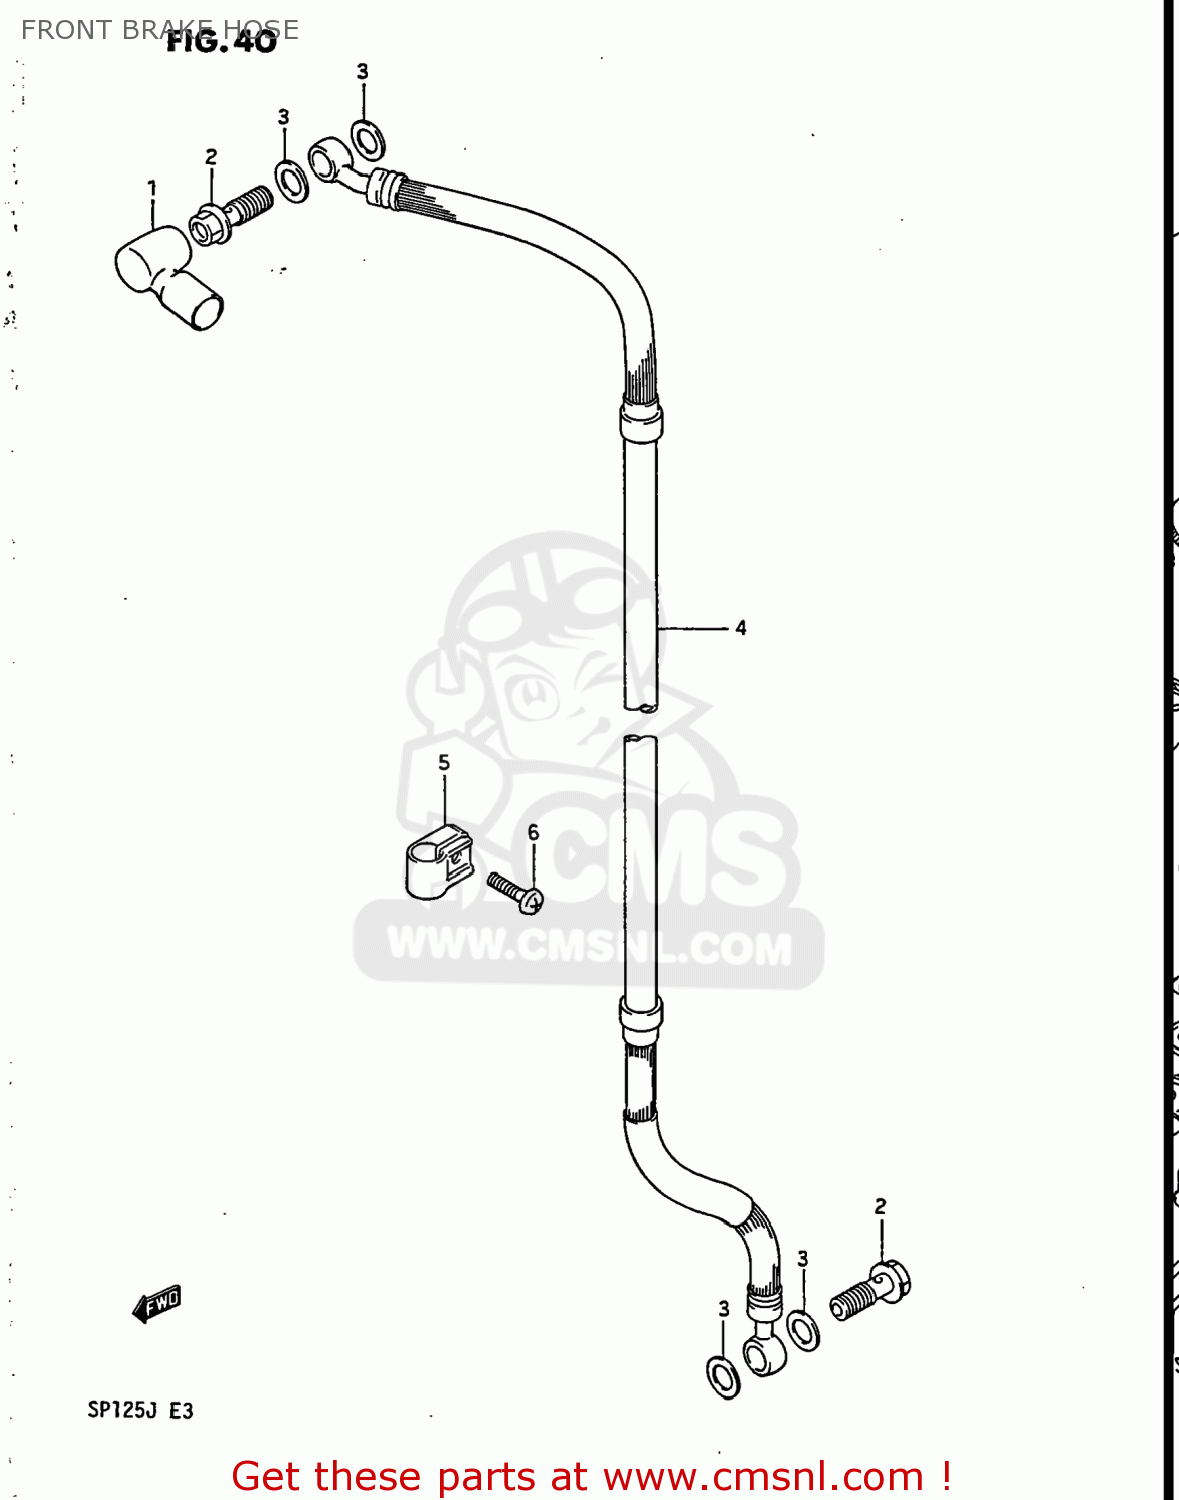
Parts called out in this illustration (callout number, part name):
1	BOOT,MASTER CYLINDER
2	BOLT UNION
3	WASHER(10X15X1.5)
4	HOSE,FRONT BRAKE
5	CLAMP,BRAKE HOSE
6	SCREW
